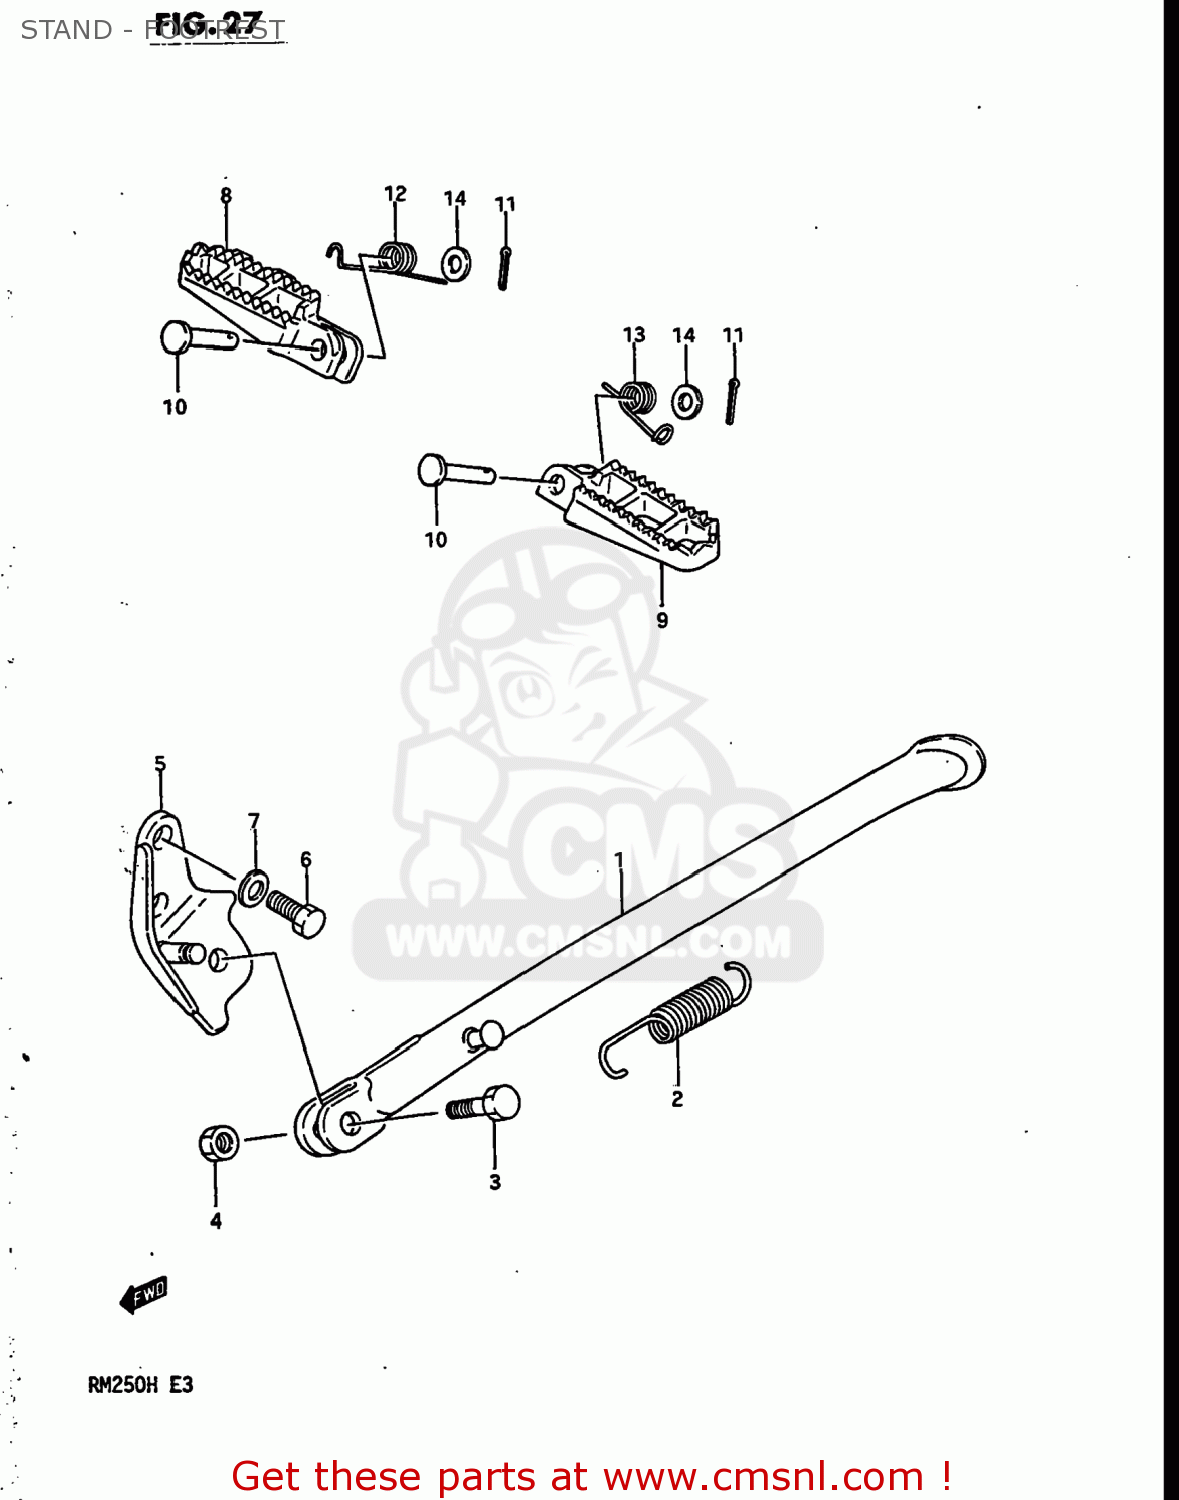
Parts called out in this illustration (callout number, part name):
1	STAND,SIDE
2	SPRING
3	BOLT(10X30)
4	NUT
5	BRACKET,SIDE STAND
6	BOLT(10X19)
7	WASHER,LOCK,10
8	FOOTREST
9	FOOTREST
10	PIN
11	PIN 20X20
12	SPRING
13	SPRING
14	WASHER
